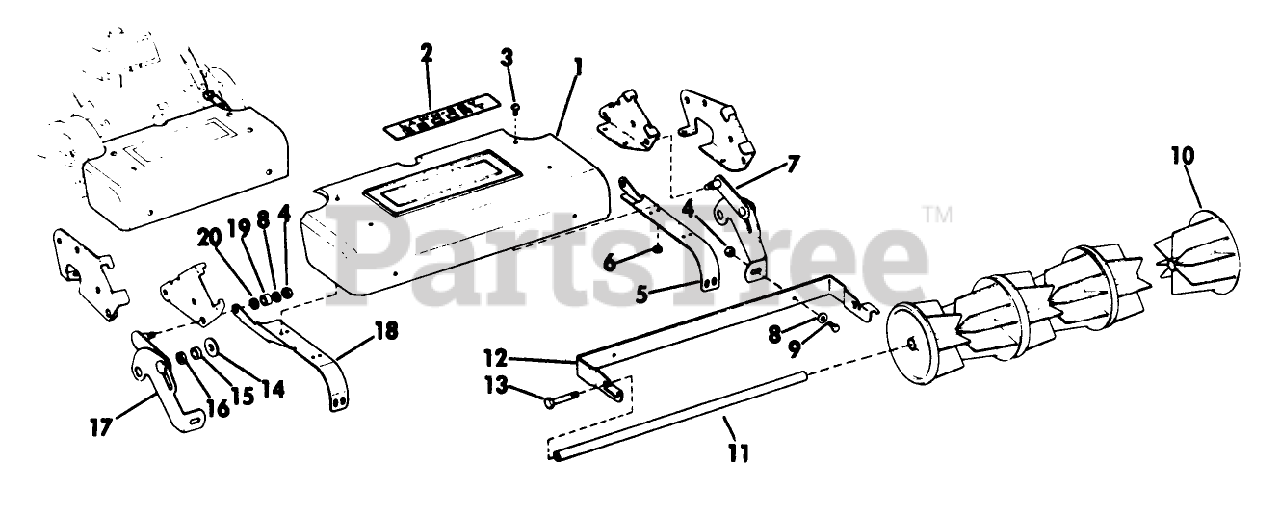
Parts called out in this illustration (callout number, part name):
1	Roller Cover Decal Assembly
14	WASHER WROUGHT
15	Spacer-Wheel-Red
17	Roller Link Assembly-Right
